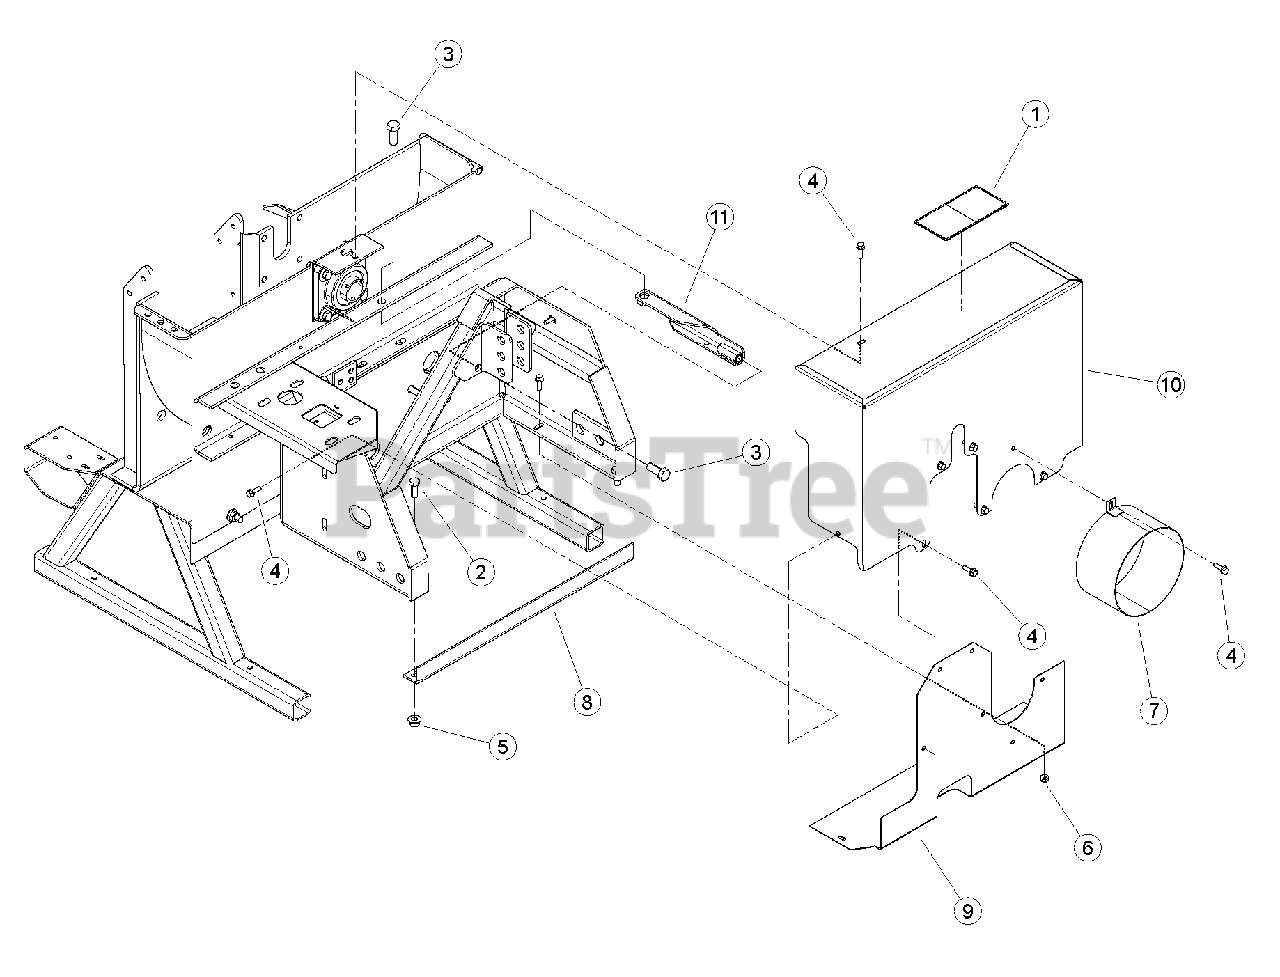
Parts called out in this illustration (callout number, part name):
1	DECAL, PTO DANGER ISO
2	BOLT, 1/2 X 1-1/4" GR5 HHCS NC ZP
3	BOLT, 5/8 X 1-1/2 HEX HD GR5 ZP
4	BOLT, 5/16 X 1 FLANGE NC
5	NUT, 1/2-13 NYLOCK FLANGE
6	NUT, 5/16-18 NYLOCK FLANGE
7	WELDMENT, PTO SHIELD
8	BRACE, 3 PT BOTTOM
9	WELDMENT, GUARD PTO LOWER BELT
10	WELDMENT, GUARD PTO UPPER BELT
11	WELDMENT, BRACE PTO 3-POINT
